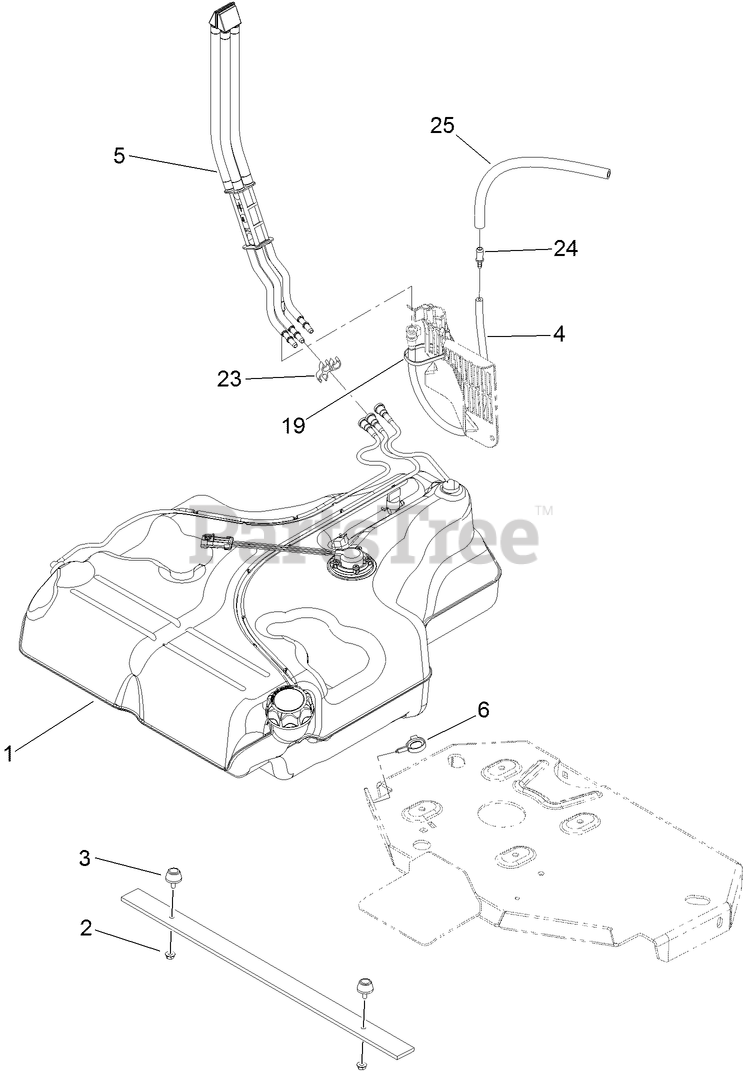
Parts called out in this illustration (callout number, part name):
1	FUEL TANK ASM
2	NUT-HF
3	BUMPER-RUBBER
4	HOSE ASM
5	FUEL MANIFOLD VENT ASM
6	CLAMP-HOSE
19	TIE-PLASTIC
23	CLIP-SPACER
24	FITTING-STRAIGHT
25	HOSE-FUEL
